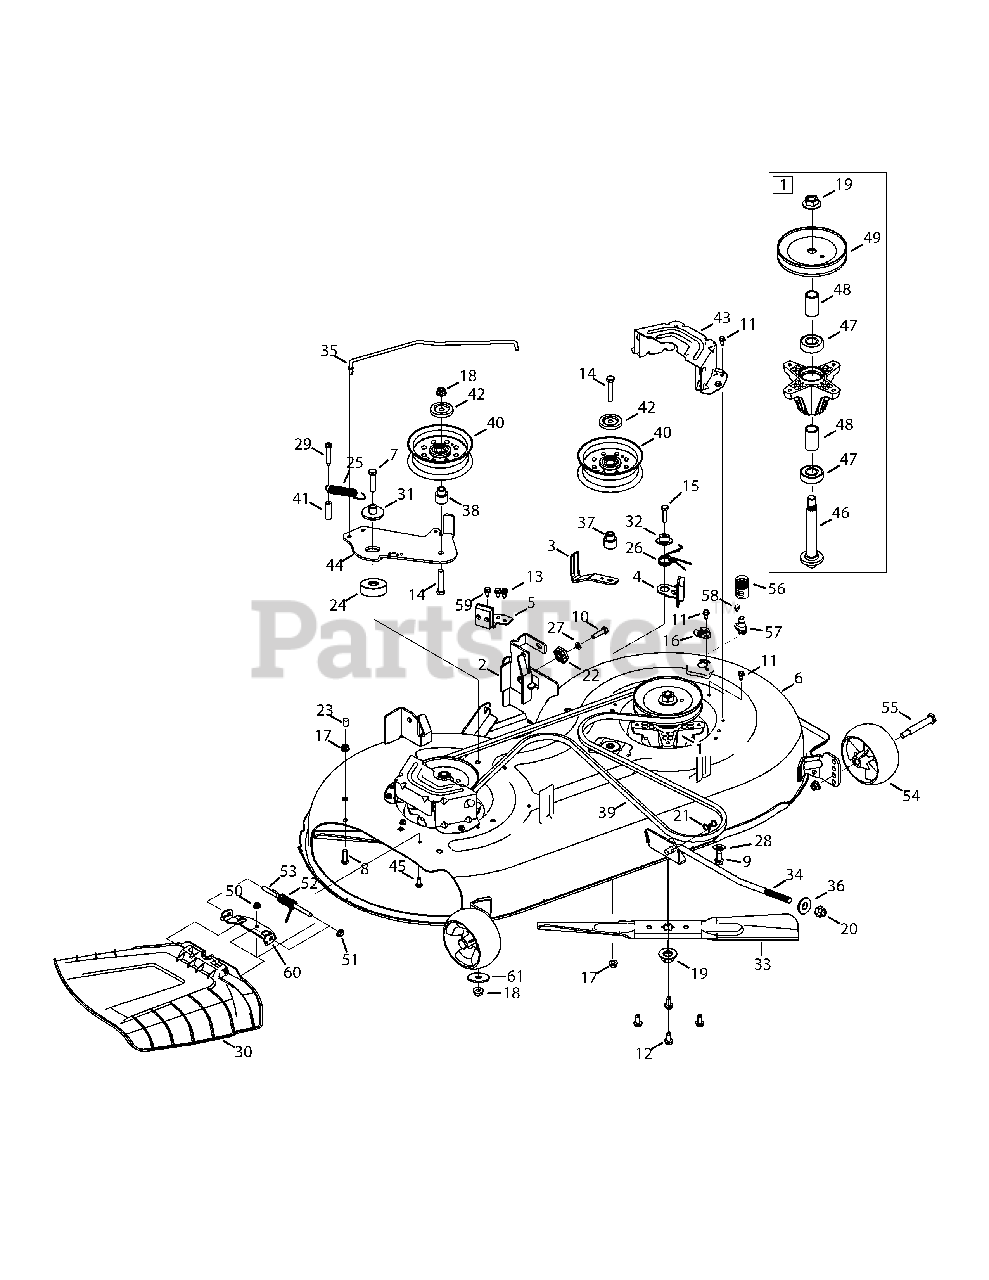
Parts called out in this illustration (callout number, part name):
1	Spindle Ass’y, Pulley, 6.2 Dia
2	Bracket Ass’y, Deck, Hanger LH
3	Belt Keeper
4	Brake Assembly, Deck, LH
5	Brake Assembly, Deck, RH
6	Deck, 42"
7	Hex Screw, 3/8-16 x 1.75
8	Hex Cap Screw, 5/16-18 x 1.00
9	Screw, Self-tapping, 5/16-18, .750
10	Hex Screw, 5/16-18, 1.25, Gr5, Std
11	Screw, Self-tapping, 1/4-20, 0.500
12	Screw, 5/16-18 x 0.750
13	Screw, M6-1 x .625
14	Hex Screw, 3/8-16, 2.00, Gr8, Std
15	Hex cap Screw, 5/16-18 x 1.25
16	Deck Wash Plug
17	Nut, Flange Lock, 5/16-18, Grf
18	Nut, Flange Lock, 3/8-16, Grf
19	Nut, Flange, 5/8-18
20	Flange Lock Nut, 1/2-13
21	Bow-Tie Cotter Pin
22	Gear, Deck, Adjustment
23	Cap, .290 x .500
24	Spacer, .385 x 1.75 x .585
25	Extension Spring, .750 X 4.77
26	Torsion Spring, LH
27	Washer, Lock, 5/16, Regular Duty
28	Flat Washer, .406 x .875 x .059
29	Screw, Self Tapping, 1/4-20, 1.50
30	Chute Deflector Assembly
31	Shoulder Spacer, .970 x .190
32	Shoulder Spacer, .75 x .145
33	Blade, Cut, 21.23" 2-In-1
34	Rod, Lift, Deck, Frt, 12.7
35	Brake Rod
36	Deck Lift Pivot Cup
37	Shoulder Spacer, Idler
38	Shoulder Spacer, Pivot Idler
39	Belt, V Type, A Sec X 96.5
40	Pulley, Idler, 4.50"Dia
41	Spacer, .260 x .375 x 1.030
42	Pulley Cap
43	Deck Belt Cover, 42
44	Deck Idler Bracket
45	Hex Cap Screw, 1/4-20 x .62
46	Shift, Spindle, 6.11.
47	Bearing, Ball, .787id x 1.85 Odx.551
48	Spacer, .792 x 1.060 x 1.860
49	Pulley, Deck, 5.4 Dia
50	Nut, Flange Lock, 1/4-20, Nylon
51	Push Cap
52	Spring, Torsion, .440 ID x 1.75
53	Hinge Pin
54	Wheel, Deck, 5.0 Dia Ball
55	Bolt, Shoulder, .496 x 2.50, 3/8-16
56	Water Nozzle Adapter
57	Deck Wash Nozzle
58	Shoulder Screw, 1/4-20 x 0.50
59	Shoulder Screw, 1/4-20
61	Flat Washer, .406 x 1.50 x .105
